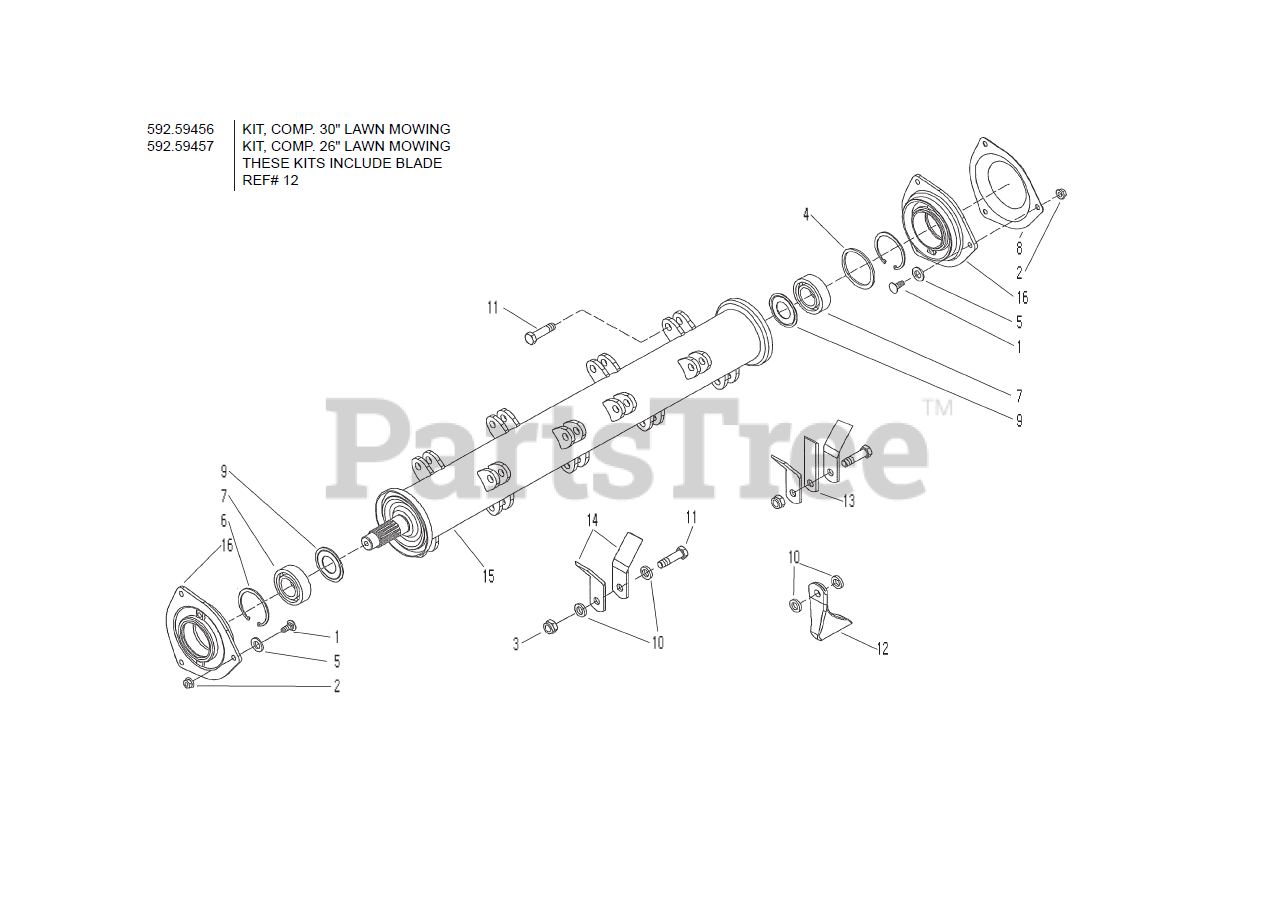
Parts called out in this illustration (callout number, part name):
1	CAPSCREW M8X25
3	LOCKNUT M12, LOW PROFILE
4A	SHIM 50X62/0.2
4B	SHIM 50X62/1.5
4C	SHIM 50X62/0.5
5	WASHER FLAT M13X24
6	SNAP RING INTERNAL D 62
7	BEARING
9	GUARD
10	SPACER
11	SCREW
12	CUP KNIFE (OPTIONAL)
13	STRAIGHT KNIFE (OPTIONAL)
14	KNIFE, FLAIL MOWER
15A	ROLLER AXLE 24IN
15B	ROLLER AXLE 30IN
16	FLANGE
17	KIT, COMP. 30" LAWN MOWING
17	KIT, COMP. 26" LAWN MOWING
